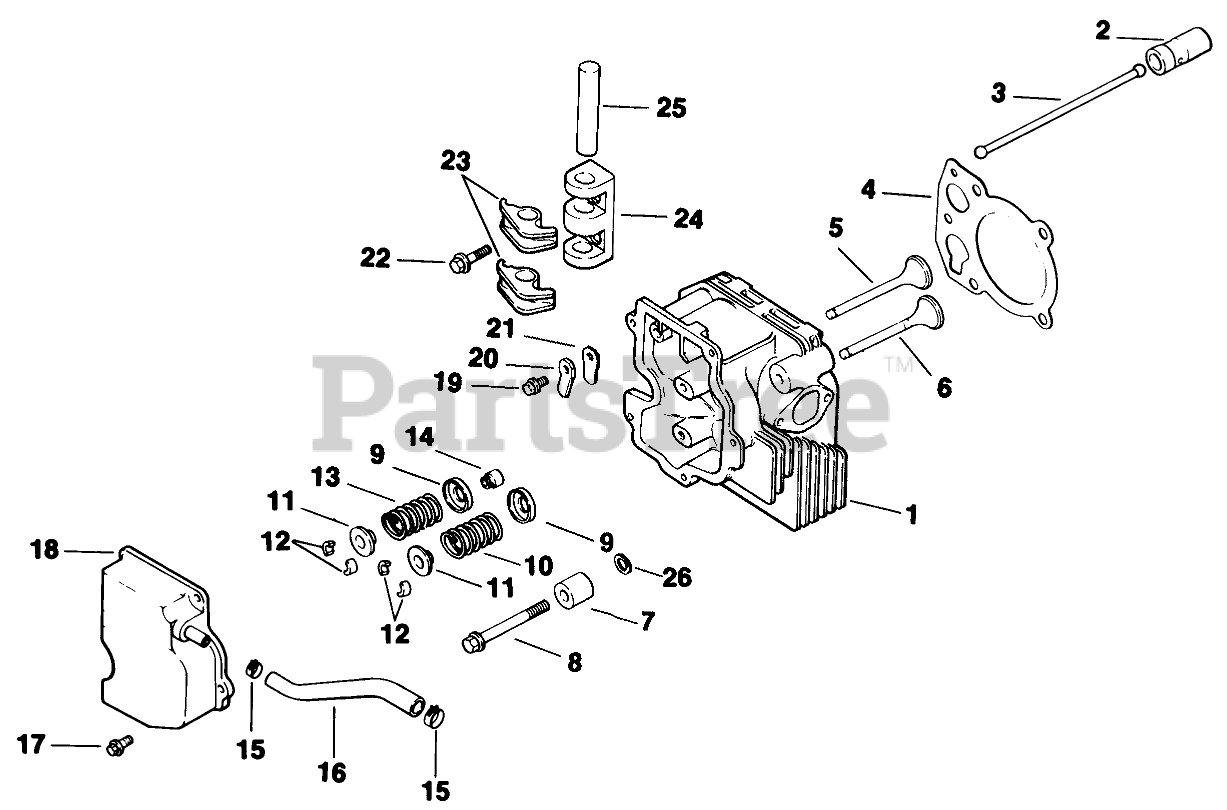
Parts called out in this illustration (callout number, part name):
1	Cylinder Head
2	Lifter-Valve
3	Rod-Push
4	Gasket-Cylinder Head
5	Valve-Intake STD
6	Valve-Exhaust STD
7	Spacer
8	Screw
9	Retainer-Spring
10	Pulley
11	Cap-Valve Spring
12	Kit-Retainer
13	Spring-Valve Intake
14	Seal
15	Clamp
16	Hose-Breather
17	Screw
18	Cover-Valve
20	Retainer-Reed
22	Screw
23	Arm-Rocker
24	Bridge-Rocker Arm
25	Shaft-Rocker Arm
26	Washer
